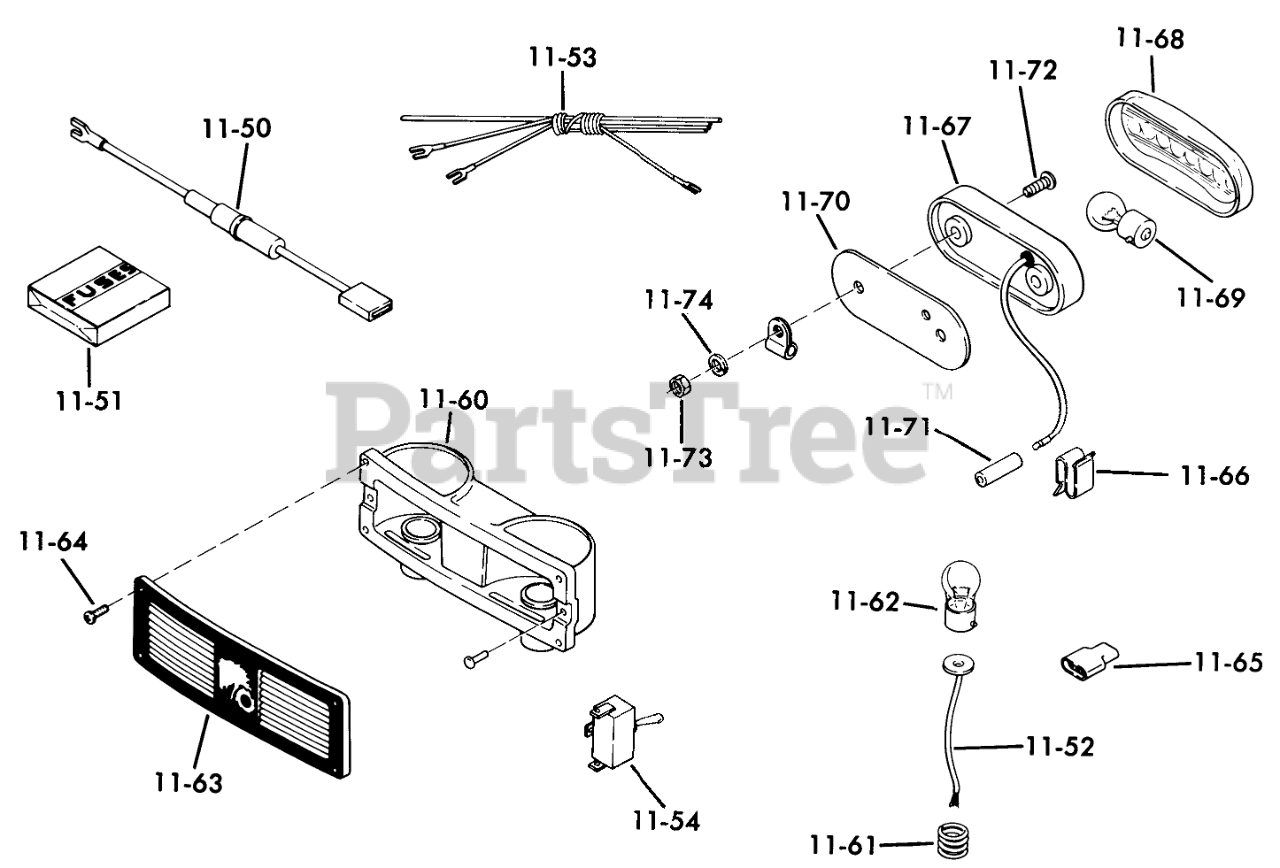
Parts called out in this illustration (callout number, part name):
11-50	ASSY FUSED CONNECTOR
11-52	WIRE ASSY
11-53	Wire Harness-Lights
11-54	SWITCH-LIGHTS
11-60	ASSY REFLECTOR HOUSI
11-61	SPRING
11-62	BULB
11-63	Lens
11-64	Pan HD Swage
11-65	CONNECTOR 3 WIRE
11-66	SPEED CLIP
11-67	Base
11-68	Lens
11-69	Bulb
11-70	Mounting Pad
11-71	CONNECTOR 2 WIRE
11-72	Screw
11-73	Nut
11-74	Lockwasher
